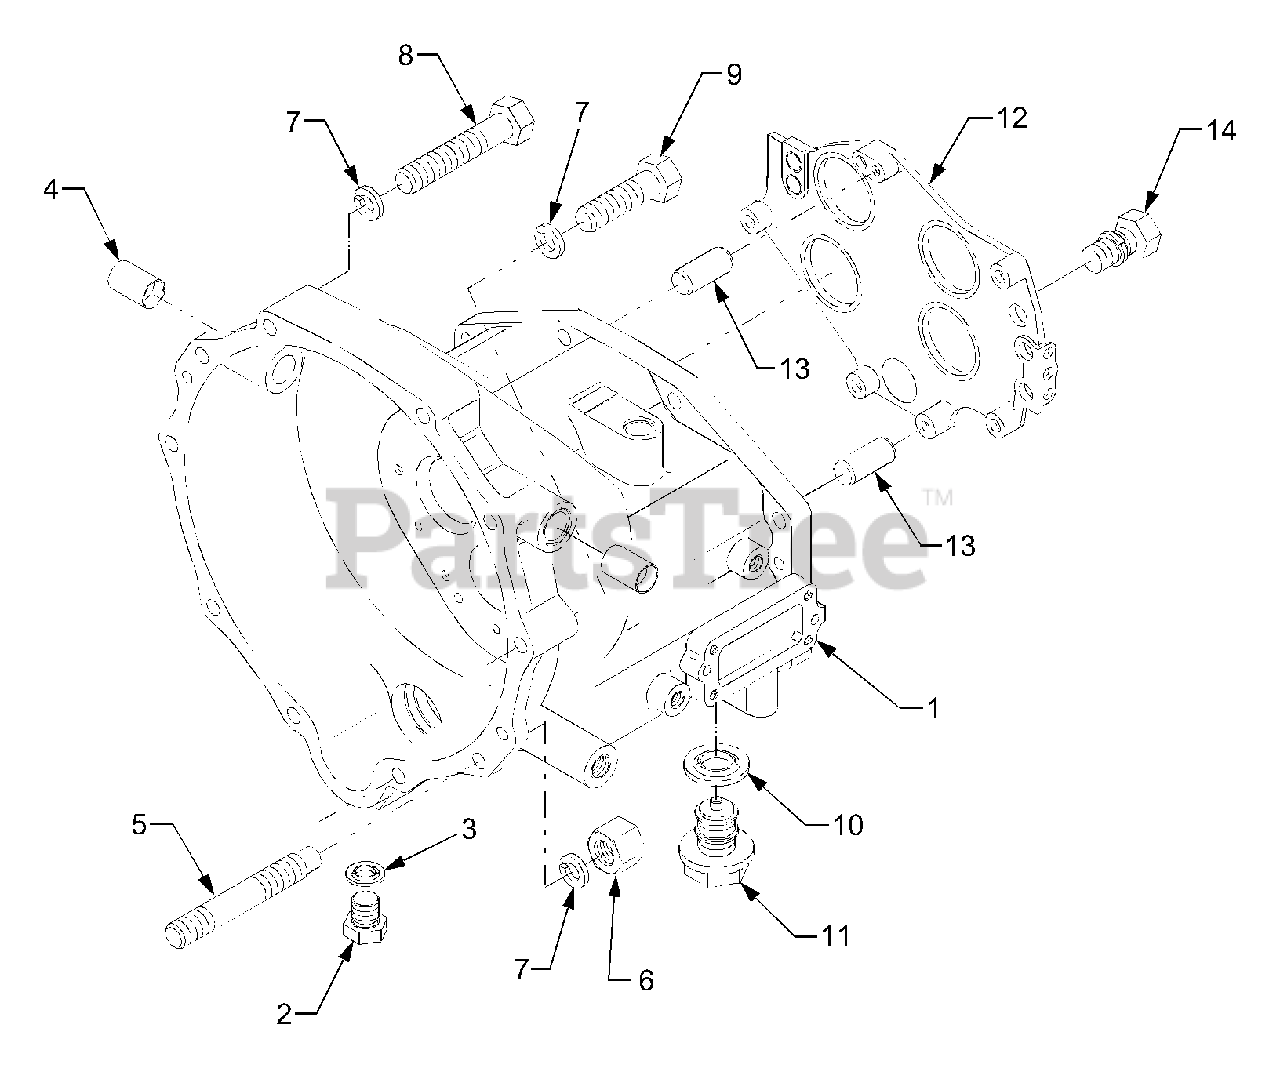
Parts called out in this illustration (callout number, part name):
1	Housing, Clutch
7	Washer, Spring
11	Plug, Drain
12	Cover, Bearing
13	Pin, Straight
